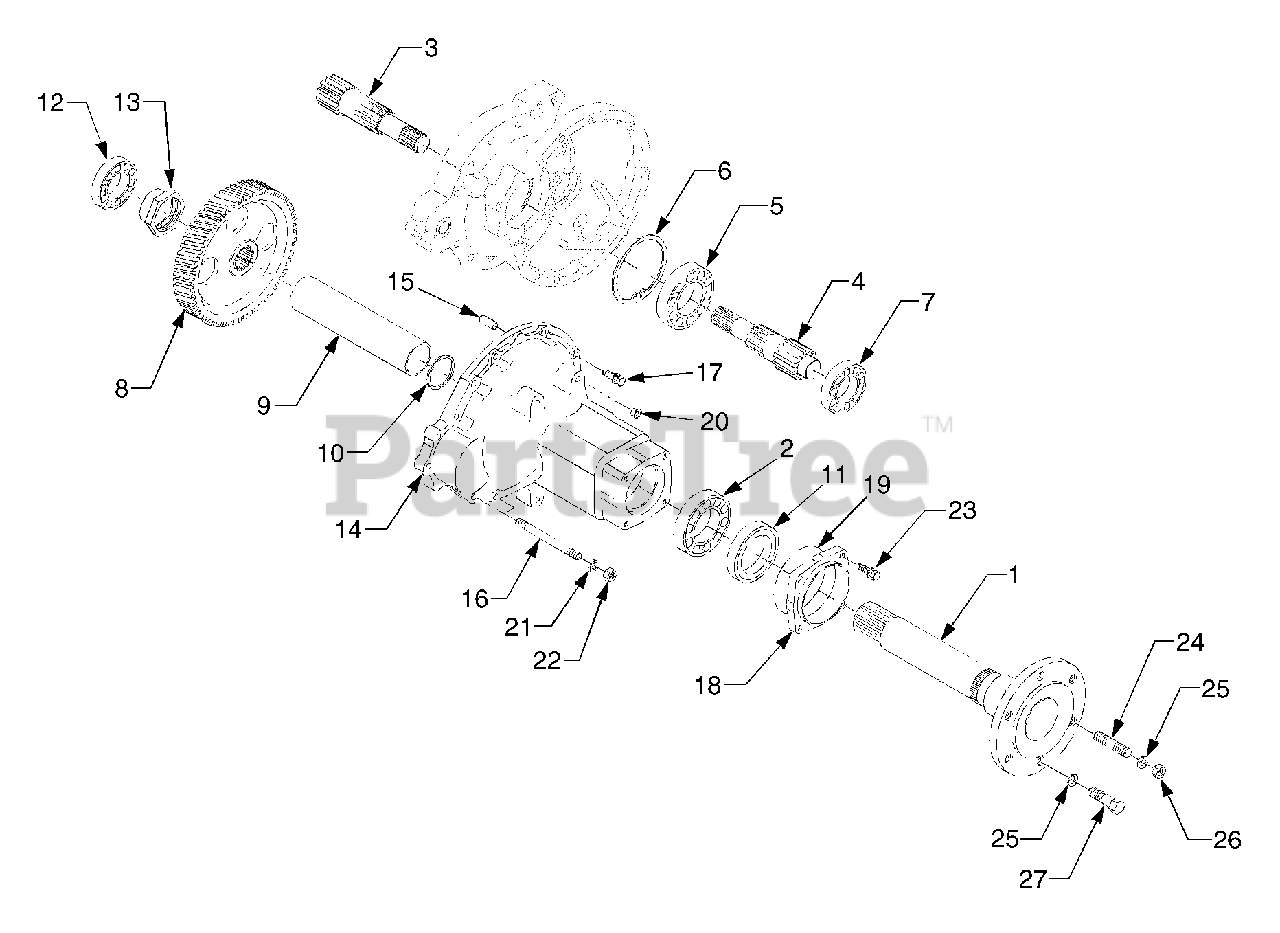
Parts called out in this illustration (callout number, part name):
2	Bearing, Ball
3	Shaft, 10 Gear(RH)
4	Shaft, 10 Gear(LH)
5	Bearing, Ball
7	Bearing, Ball
12	Bearing, Roller
14	Case, Rear Axle
15	Pin, Straight
18	Cover, Rear Axle Case
21	Spring Washer
25	Washer, Spring
